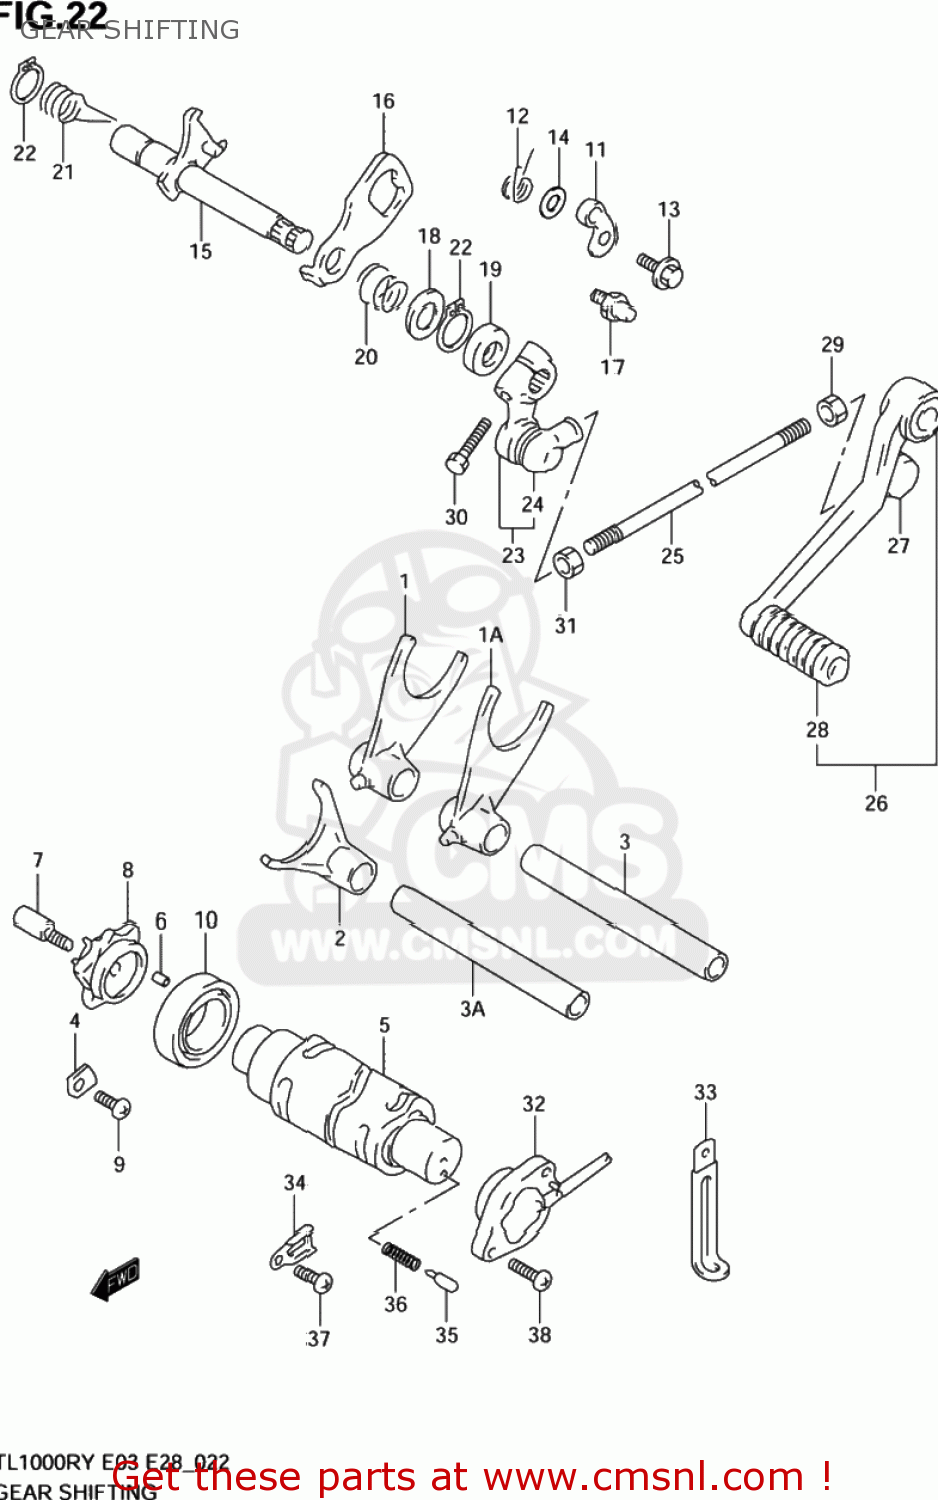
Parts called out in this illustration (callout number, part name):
1	FORK,GEAR SHIFT
1A	FORK,GEAR SHIFT NO.1
2	FORK,GEAR SHIFT NO.3
3	SHAFT,GEAR SHIFT FORK
3A	SHAFT,GEAR SHIFT FORK NO.2
4	RETAINER
5	CAM,GEAR SHIFT
6	PIN
7	PIN,SHIFT CAM DRIVEN GEAR
8	PLATE,GEAR SHIFT CAM
9	SCREW
10	BEARING
11	STOPPER,GEAR SHIFT CAM
12	SPRING,SHIFT CAM STOPPER
13	BOLT(6X14.3)
14	WASHER
15	SHAFT,GEAR SHIFT
16	PLATE,GEAR SHIFT CAM DRIVE
17	STOPPER,GEAR SHIFT CAM
18	SHIM(14X22X1)
19	SEAL,OIL(14X22X6)
20	SPRING
21	SPRING
22	CIRCLIP
23	ARM,GEAR SHIFT LINK
24	COVER,DUST
25	ROD,GEAR SHIFT LINK
26	LEVER ASSY,GEAR SHIFT
27	COVER,DUST
28	RUBBER,GEAR SHIFT PEDAL
29	NUT
30	BOLT
31	NUT
32	BASE ASSY,GEAR SHIFT TERMINAL
33	CLAMP(L:65)
34	CLAMP,GENERATOR LEAD WIRE
35	PIN(5X15.5)
36	SPRING
37	SCREW
38	SCREW
